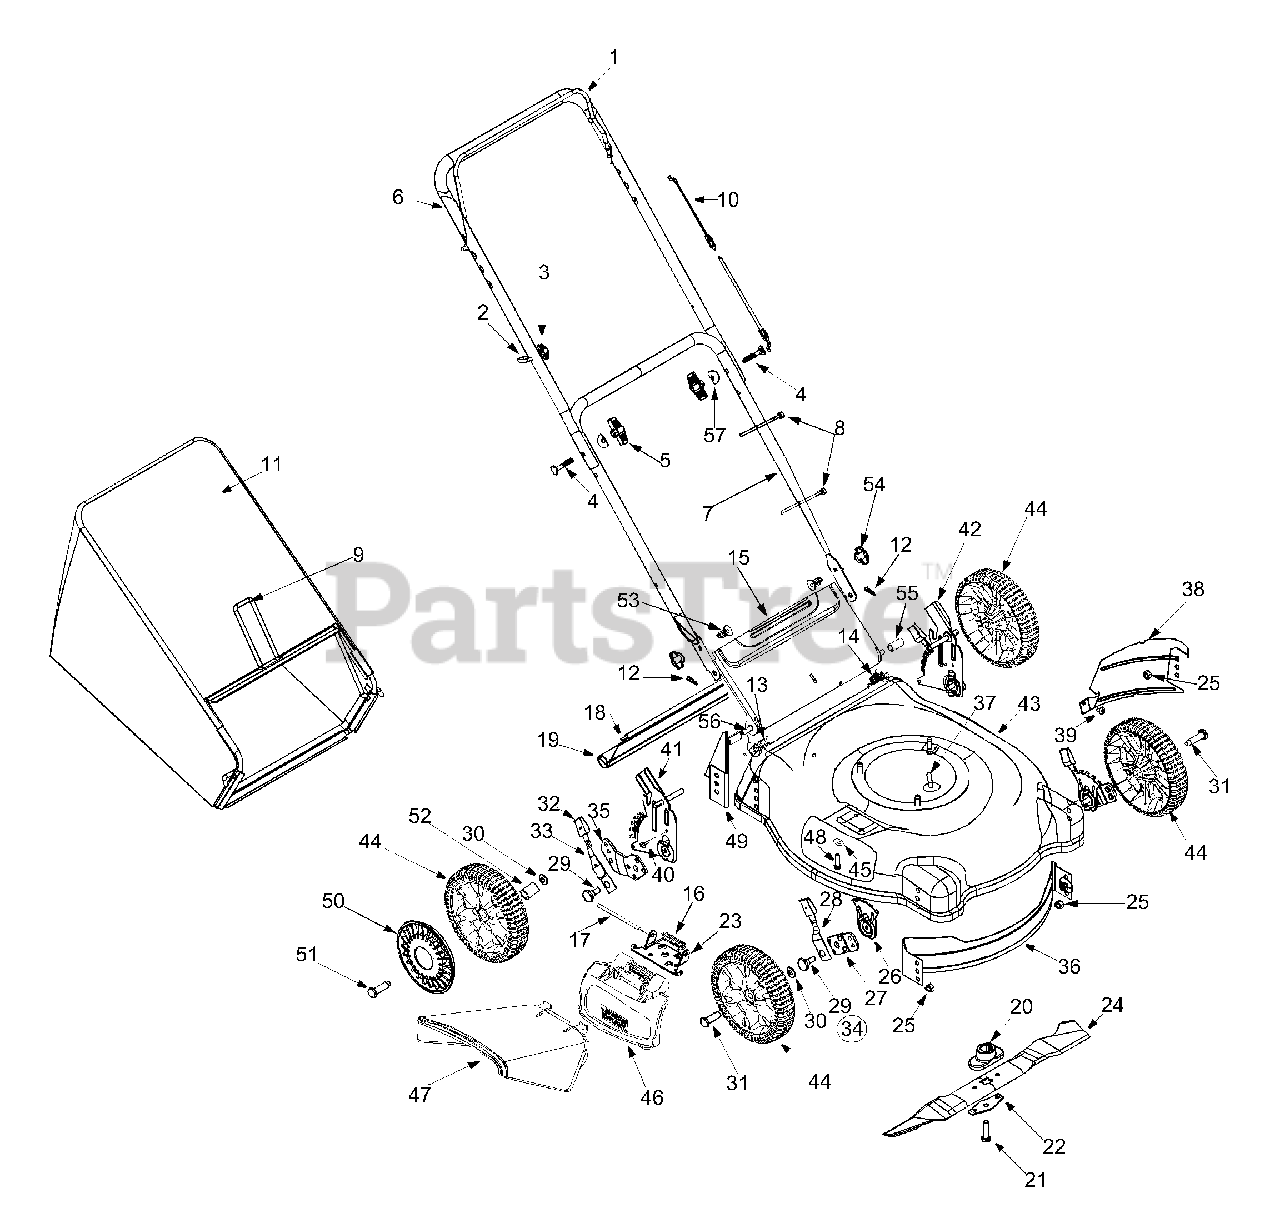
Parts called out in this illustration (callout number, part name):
2	Rope Guide
3	Handle Knob 1/4-20 Thd.
4	Curved Hd. Bolt 5/16-18 x 2"
5	Hand Knob
8	Cable Tie
10	Control Cable
11	Grass Bag (soft top w/logo)
12	Int. Cotter Pin 5/16" Dia.
13	Door Spring - R.H.
14	Door Spring - L.H.
15	Rear Discharge Door
16	Torsion Spring
17	Hinge Pin
18	Wire Rod
19	Rear Flap
20	Blade Adapter w/Star
21	Hex Bolt 3/8-24 x 1.5" Lg.
22	Blade Bell Support
23	Deflector Chute Adapter
24	21" Mulching Blade w/Star
25	Flange Nut 3/8-16 Thd.
26	Height Adj. Plate
28	Front Spring Lever
29	Shld. Bolt.5" Dia. x.357"
30	Bell Washer.38" I.D. x.88" O.D.
31	Front Axle Bolt
32	Spring Lever Knob
33	Rear Spring Lever
34	Height Adj. Assy. Comp. - RH
35	Pivot Bar R.H.
39	Torx Mach AB-Tap Scr. 1/4 x.62"
40	Hex Ind Wash. Scr. 1/4-14:.625
45	Bell Washer 1/4" I.D.
46	Hinged Mulching Plug
47	Chute Deflector: Side Discharge
48	Hex Hd Self-Tp Scr. 1/4-20 x.5"
50	Hub-Cap- Rad. Spoke- Yellow
51	Rear Axle Bolt
52	Spacer
53	Hex Carriage Screw 1/4-20
54	Wing Nut
55	Spacer,.375OD x.50ID
56	Rear Door Pivot Rod
57	Shoulder Washer
